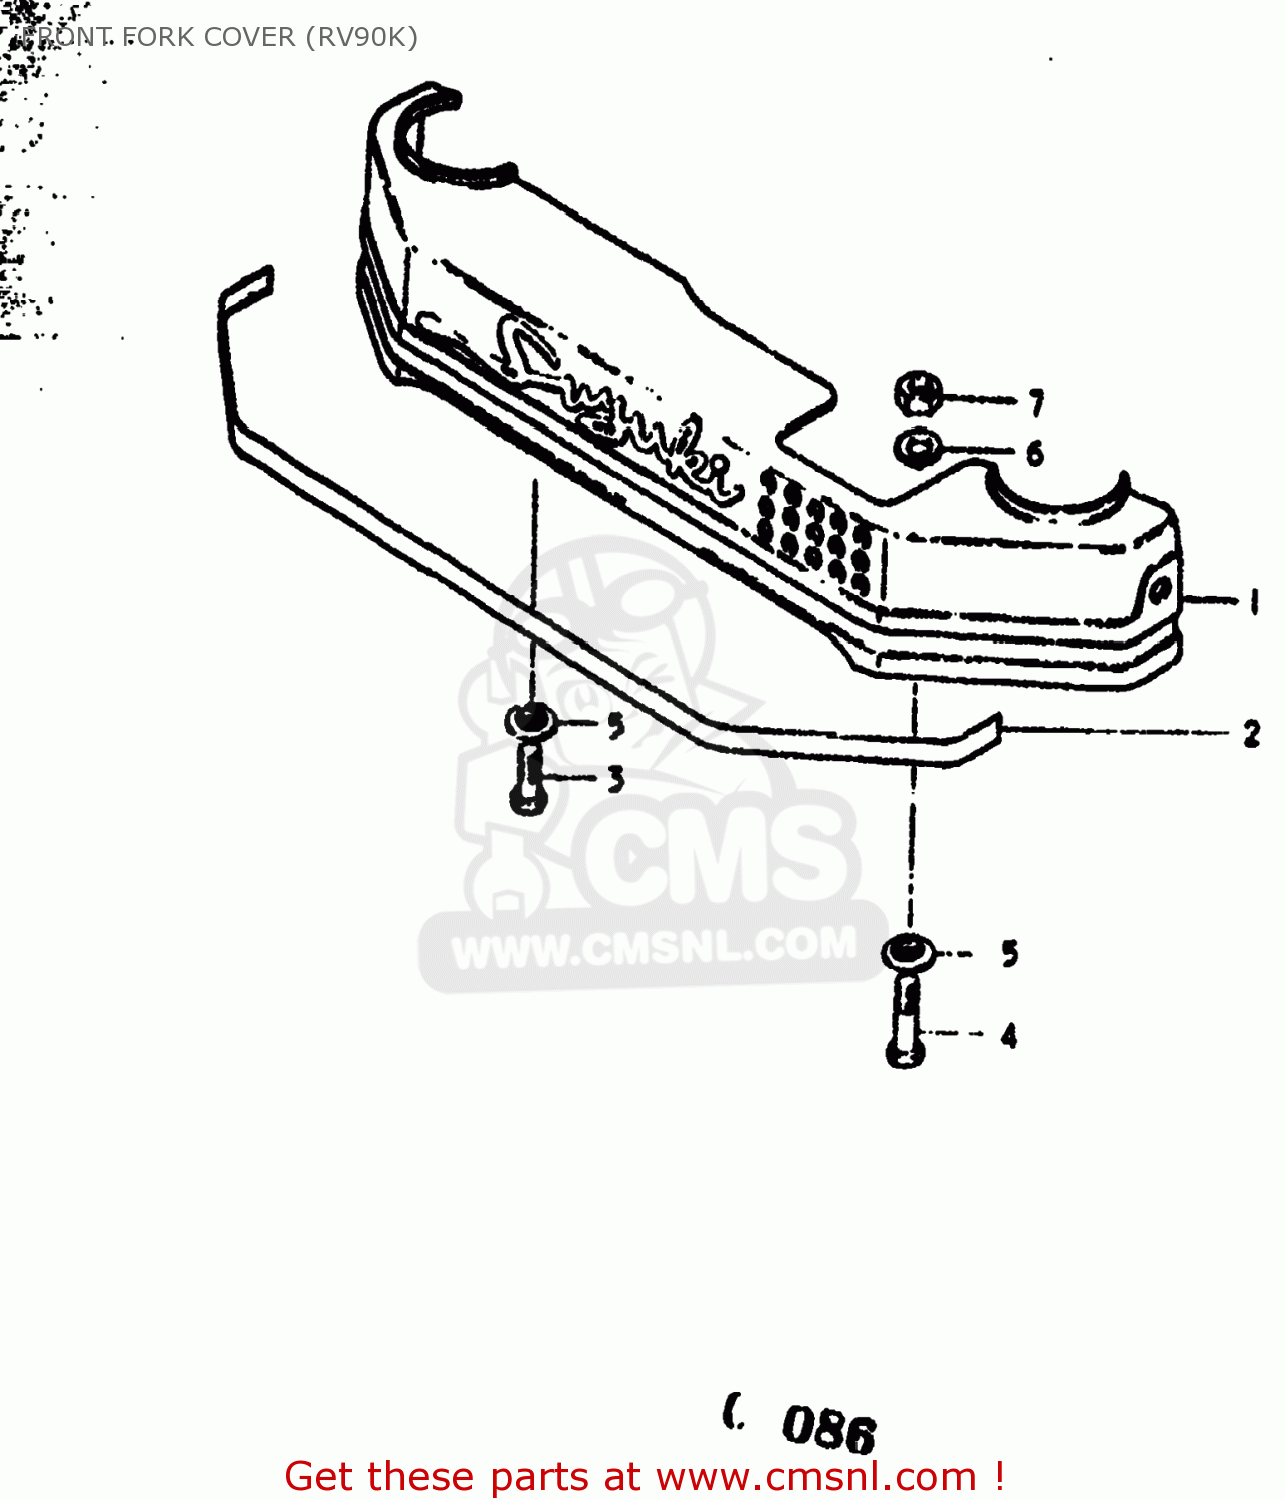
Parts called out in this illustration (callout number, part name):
1	HOUSING ASSEMBLY,HEADLAMP
2	TAPE,FUEL TANK
3	BOLT
4	BOLT
5	WASHER
6	LOCK WASHER
7	NUT
